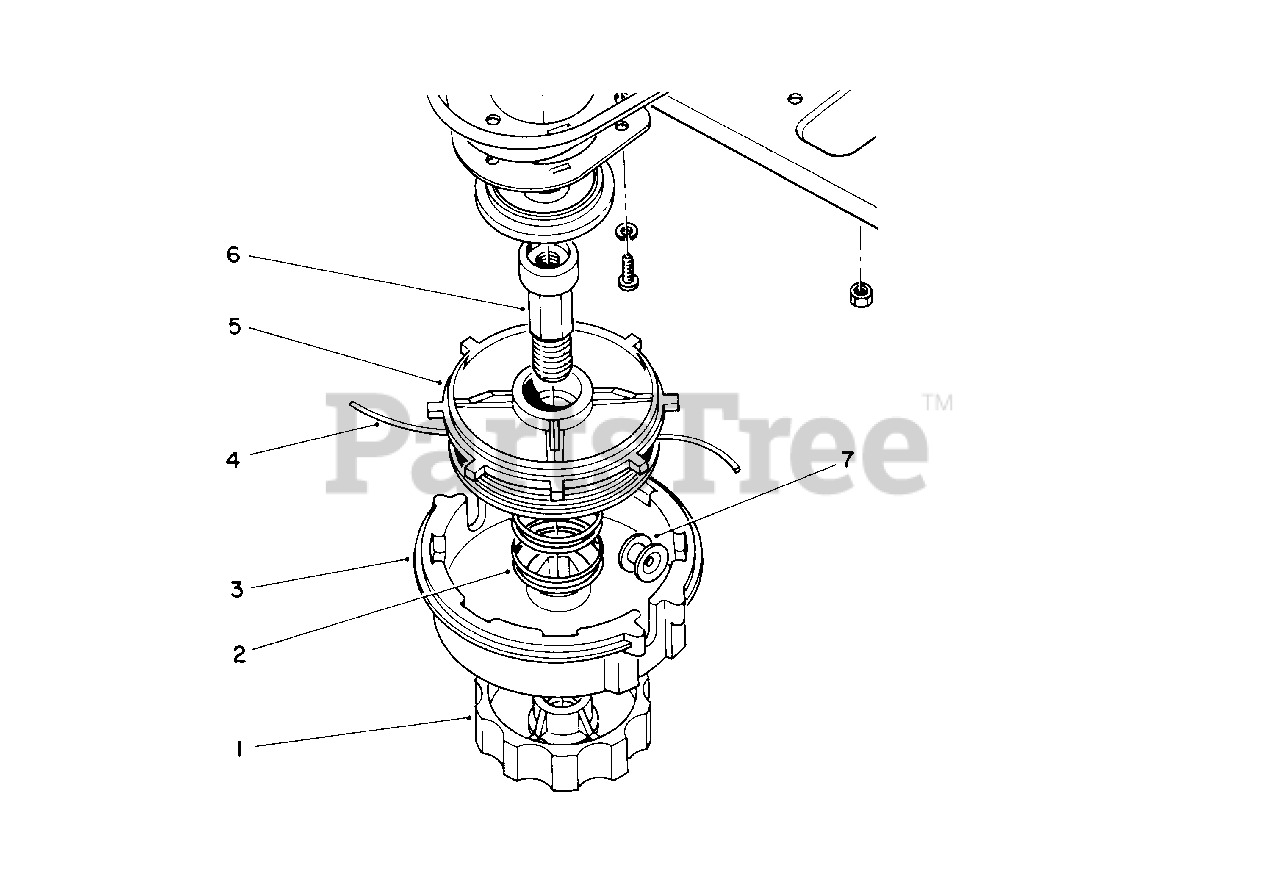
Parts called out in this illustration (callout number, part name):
1	Knob-L.H.
3	Spool Housing
5	Spool-Inner
